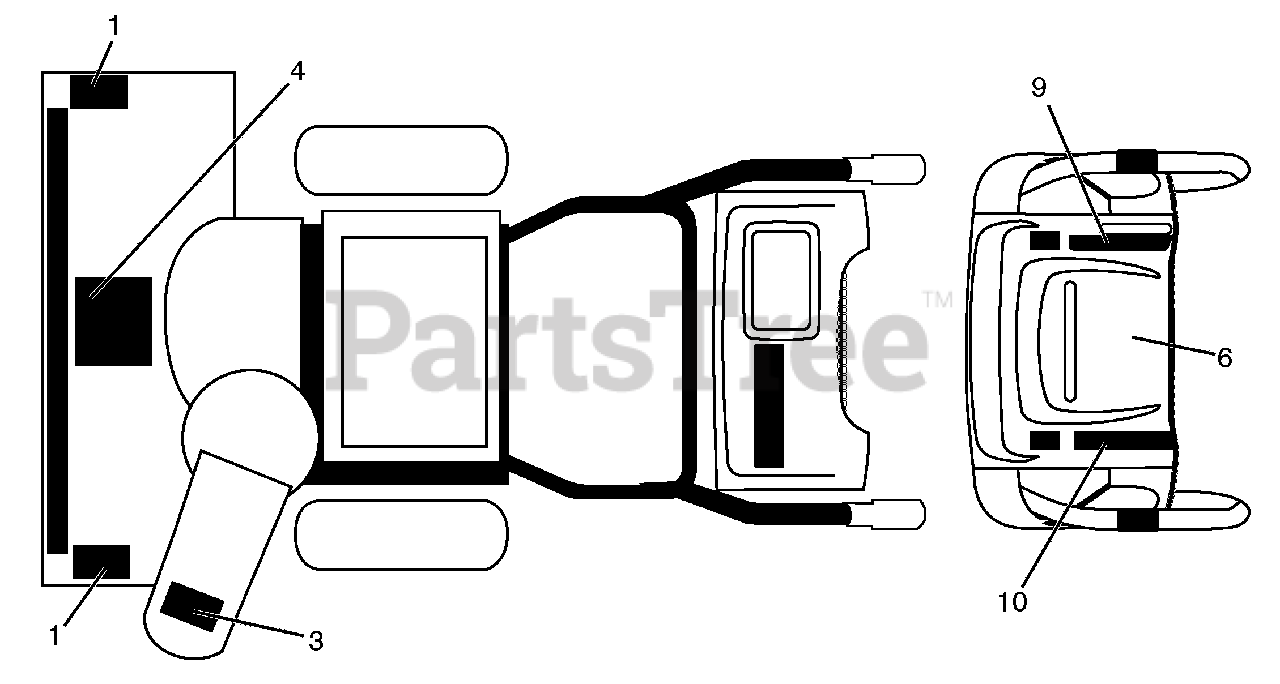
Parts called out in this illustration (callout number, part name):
1	DECAL, DANGER
3	DECAL, DANGER, DEFLECTOR
4	DECAL, DANGER
6	DECAL, INSTRUCTION
9	DECAL, SPEED CONTROL
10	DECAL, LH TRIGGER
10	OWNER'S MANUAL, ENGLISH
10	OWNER'S MANUAL, FRENCH
